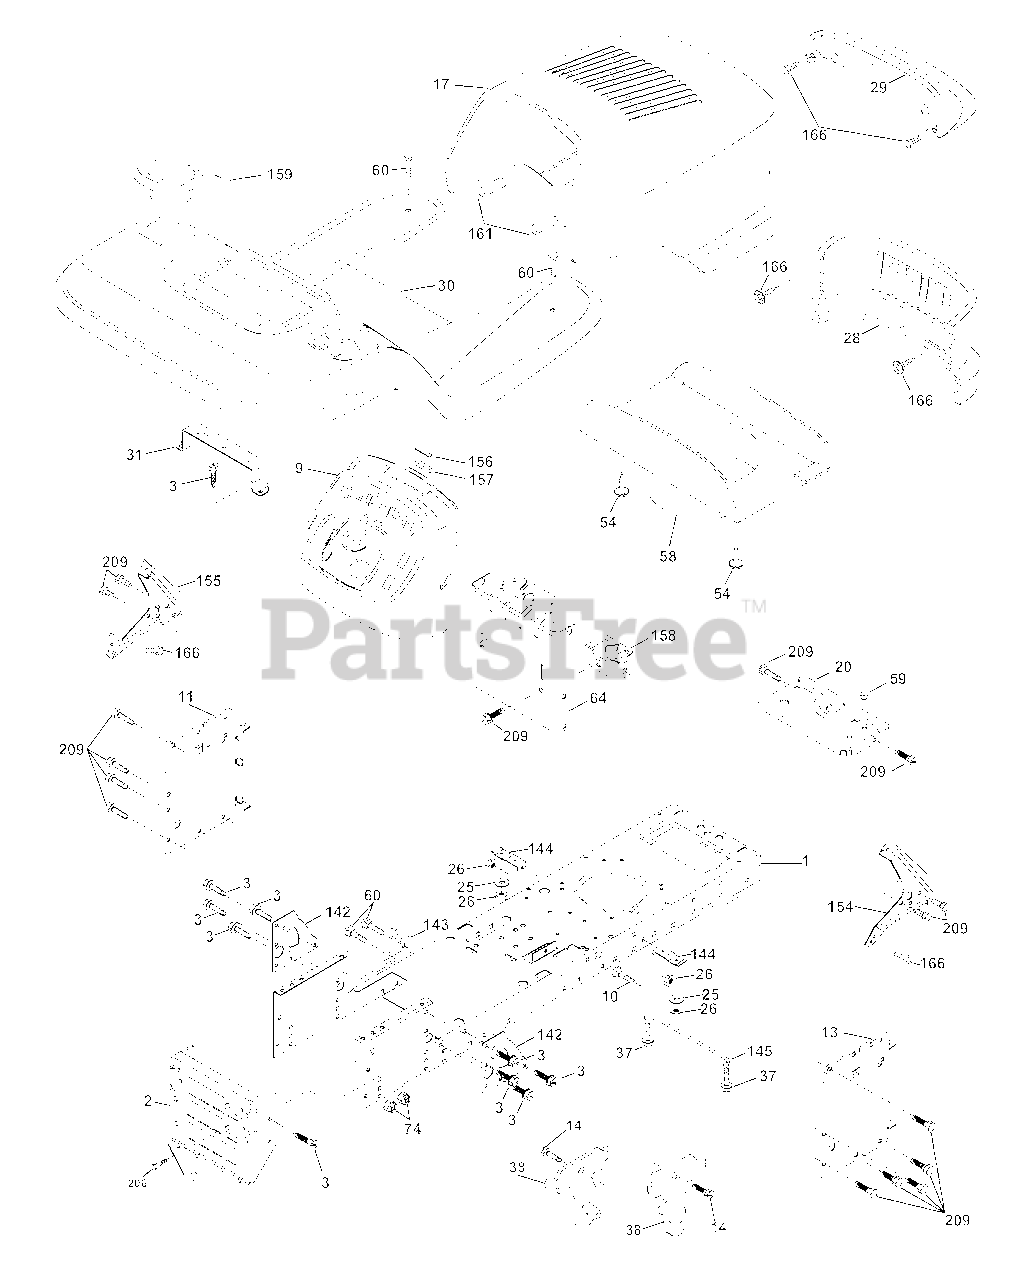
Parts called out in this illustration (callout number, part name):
1	Chassis
2	Drawbar
3	Screw 3/8-16x3/4
9	Dash
10	Bolt Carriage 3/8-16 x 1
11	Panel Dash Lh
13	Panel Dash Rh
17	Hood
18	Bumper Hood
20	Plate Battery
25	Washer 13/32 X 13/16 X 12 Ga
26	Nut Lock Hex W/Ins 3/8-16 Unc
28	Grille
29	Lens
31	Bracket Fender
37	Screw Thdrol 6/16-18 x 1/2 TYT
38	Bracket, Asm. Pivot Mower Rear
54	Screw Hex Wshd 8-18 x 7/8
58	Duct Hood
59	Bushing Snap
60	Bolt Rd Hd Sqnk 3/8-16 Unc x 3/4
64	Dash Lower
74	Nut Crownlock 3/8-16 Unc
142	Plate Reinforcement STLT
143	Bracket Swaybar Chassis
144	Bracket Footrest
145	Rod Pivot Chassis/Hood
154	Bracket Dash Rh
155	Bracket Dash Lh
156	Striker Plate
157	Magnet Stealth
158	Bracket Parking Brake
159	Cupholder
161	Extrusion Bumper
166	Screw Hw Hd Hi-Lo #13-16 x 3/4
206	Bolt Shoulder 5/16-18
209	Screw Hexwsh Thdrol 3/8-16 x 3/4
213	Skirt Grille Lh
214	Skirt Grille Rh
